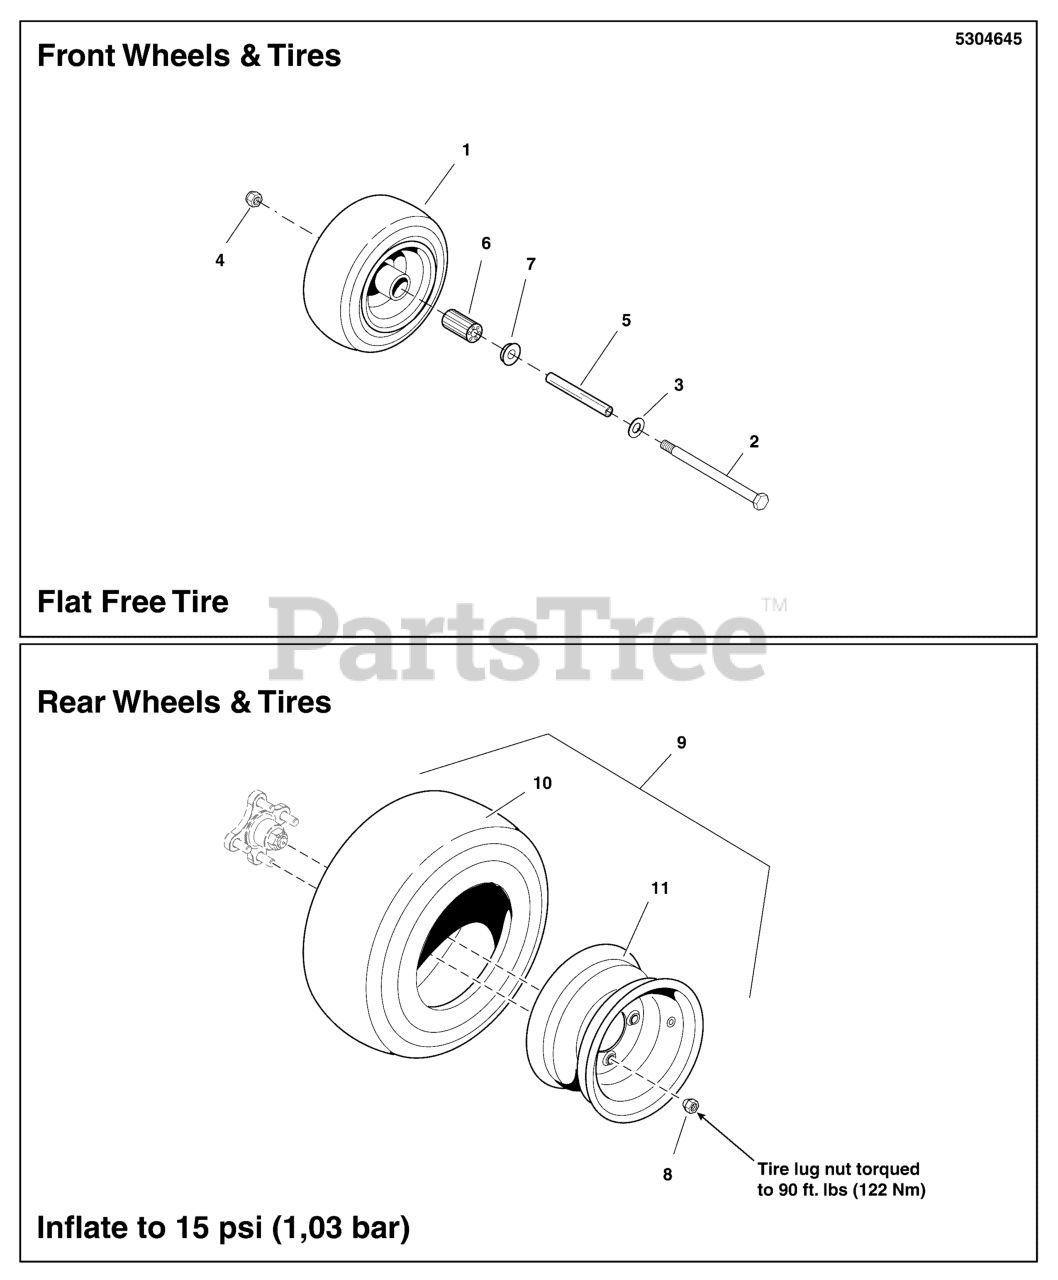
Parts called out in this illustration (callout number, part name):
1	TIRE ASSM, 11 X 4 - 5, FF / CB
2	BOLT, 1/2-13 X 7 GD5 CZ
3	WASHER, 1/2 SAE
4	NUT, Hex Flange, Nylock, 1/2-13
5	CASTER AXLE DDSH
6	BEARING, ROLLER
7	BEARING, RETAINER
8	NUT, 1/2-20, FOR WHEEL BOLT SILVER
9	TIRE ASSM, 20 X 7 - 10, TURF, 4 BOLT
10	TIRE, 20 X 7 -10 NHS, TURF MASTER
11	WHEEL, 10 X 6.00 4/4 SOLID, F237
